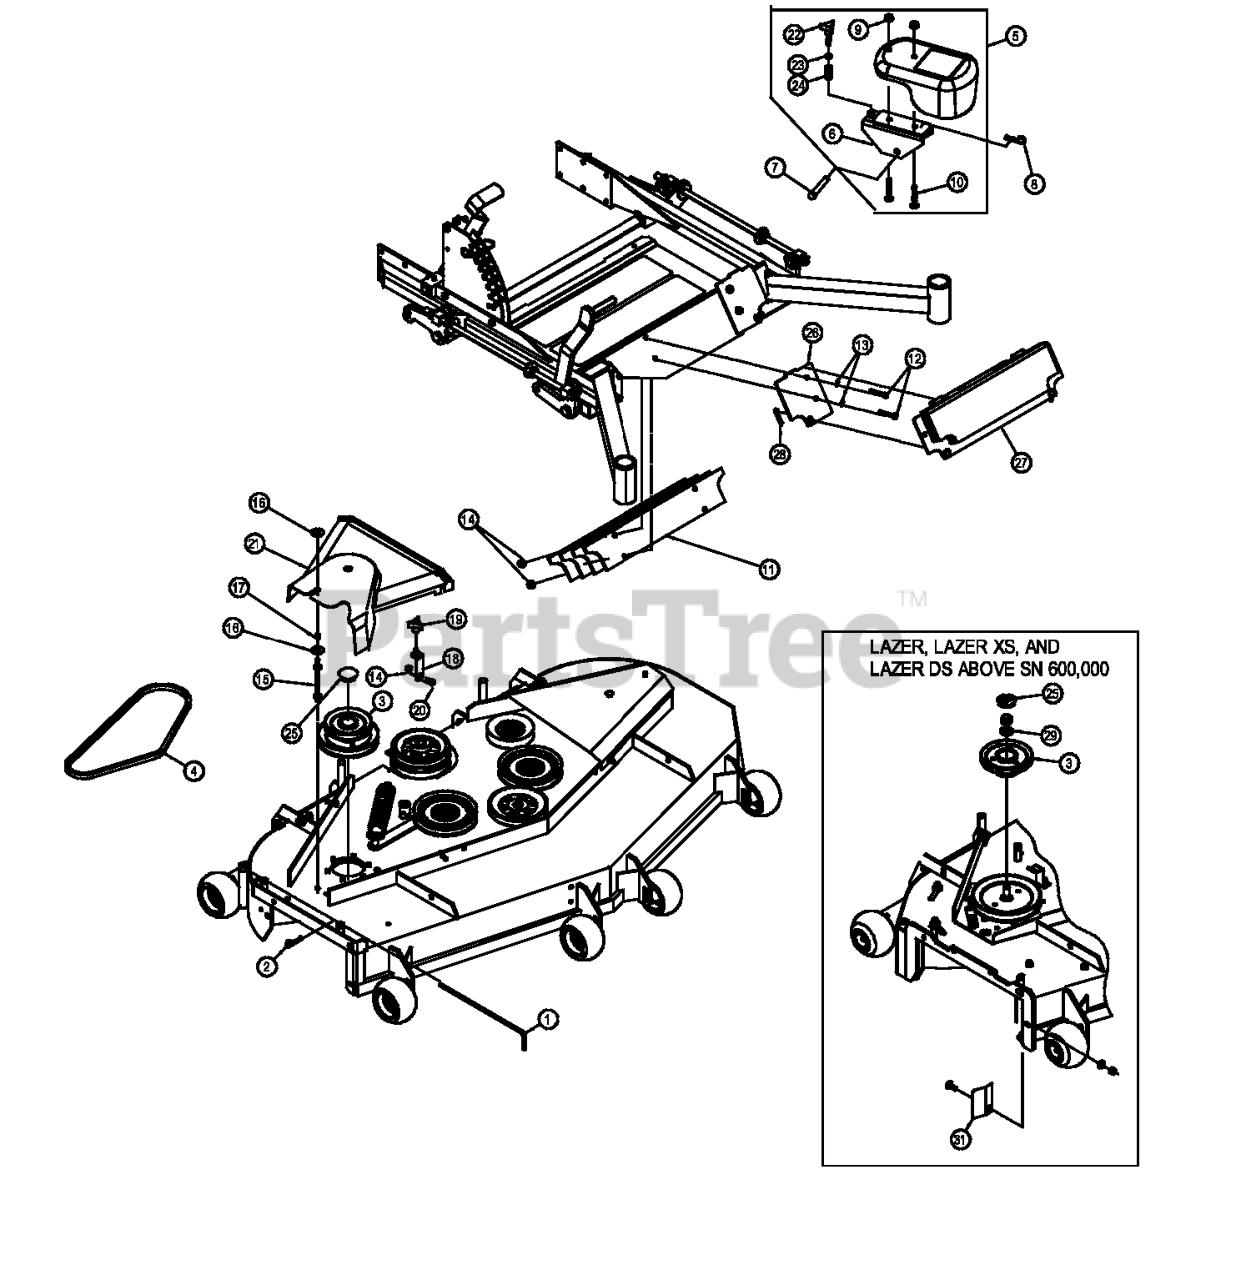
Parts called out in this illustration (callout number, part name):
1	Pin, Chute Pivot
2	Hairpin, Cotter
6	Wld, Weight Bracket 2.0
7	Pin, Clevis
8	Hairpin, Cotter
9	Nut, Whizlock 3/8-16
10	Screw, Sq Head 3/8-16 x 2 1/2
11	Plate, Weight
12	Screw, HH 5/16 -18 x 1 3/4
13	Washer, 5/16 SAE
14	Nut, Whizlock 5/16-18
15	Stud, Belt Shield
26	Plate, Weight Mounting
27	Asm, Weight Plate W/Decals
28	Hairpin, Cotter
29	Washer, 5/8 SAE
30	Template, Drill
31	Deflector
